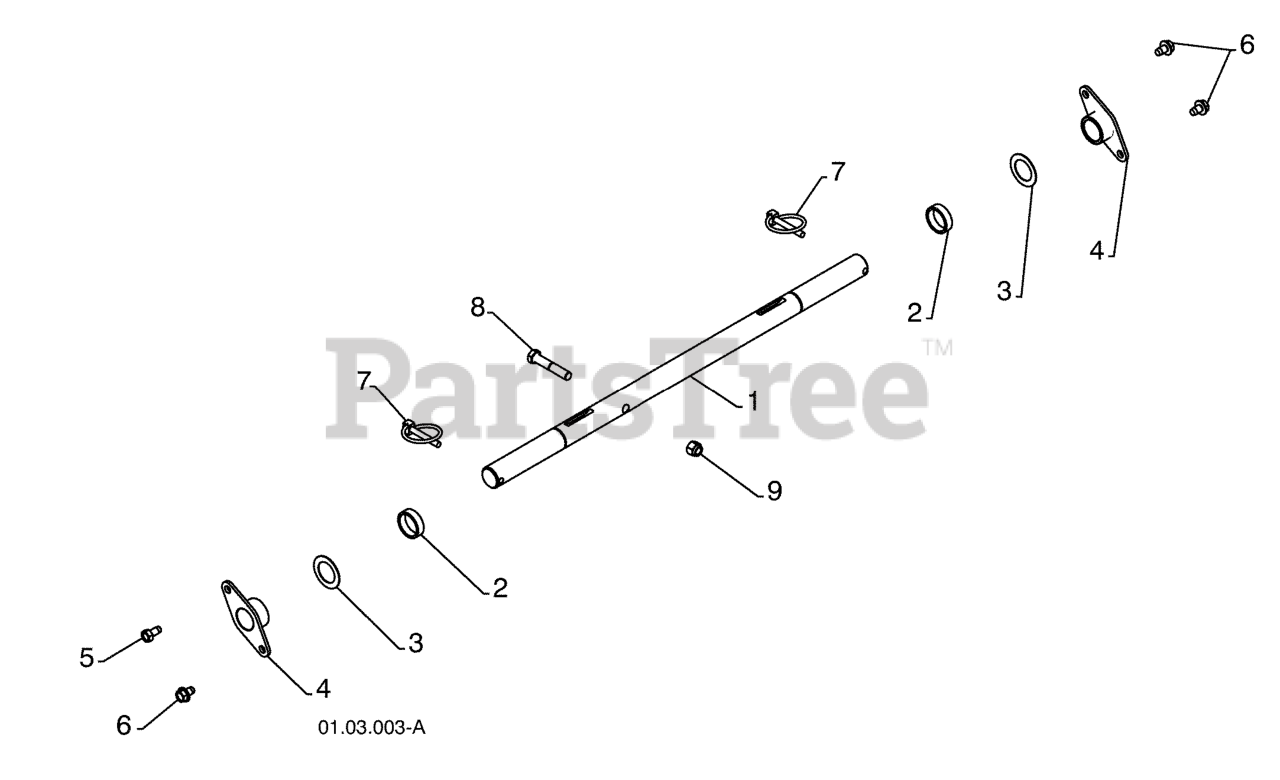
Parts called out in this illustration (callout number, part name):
1	SHAFT.AXLE.POWER.STEERING.HYD
2	SPACER.AXLE.RH
3	WASHER TRUST 1"
4	BEARING, AXLE
6	BOLT 5/16-18 X .500
7	PIN KLIK, 1/4
8	CAP.SCREW.HEX.HD.3/8-16
9	NUT
